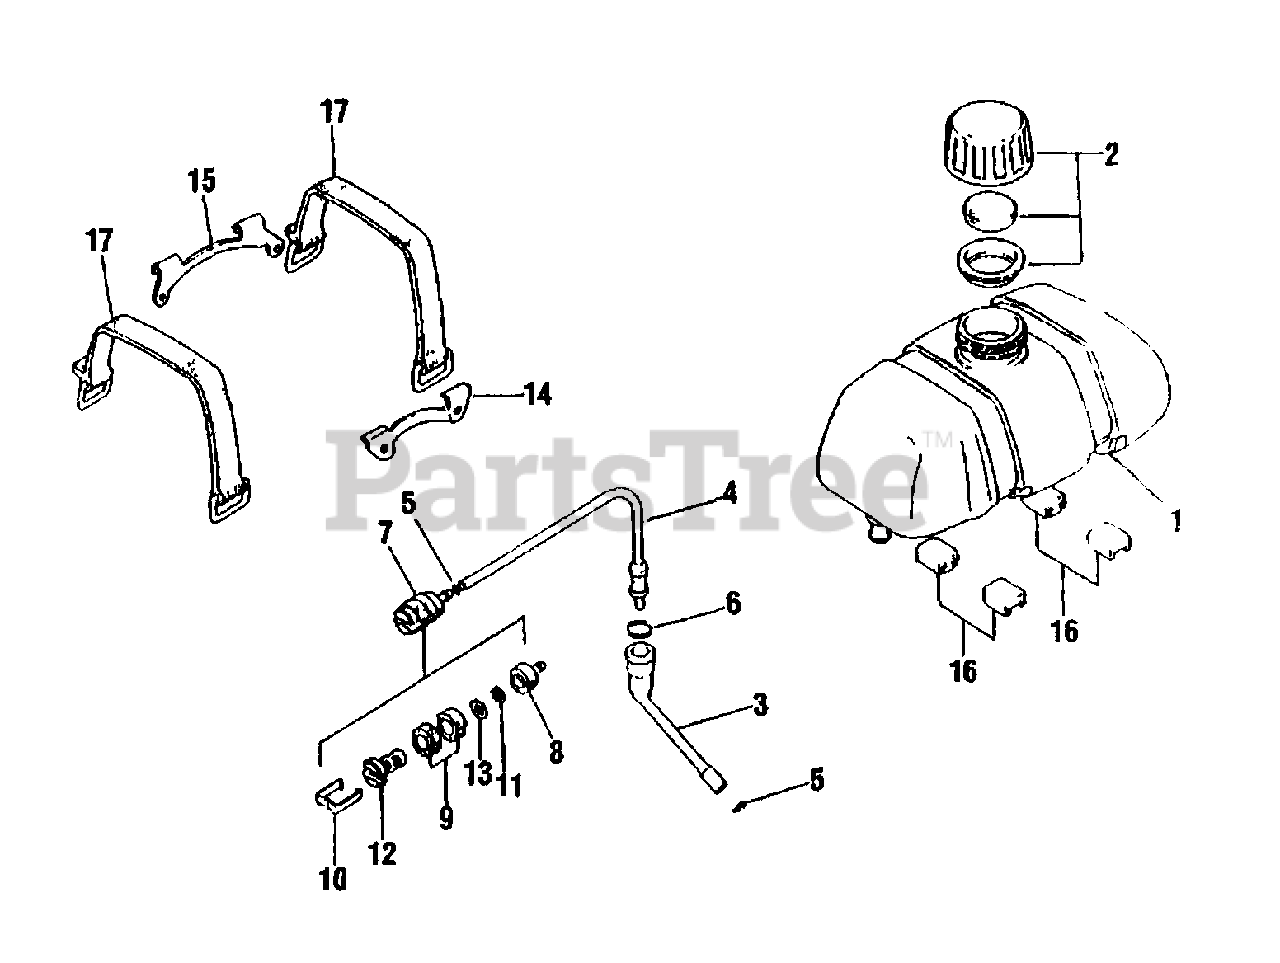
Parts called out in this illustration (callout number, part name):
1	TANK, FUEL
2	CAP, FUEL
3	PIPE - FUEL
4	TUBE, SUCTION
5	CLAMP
6	CLAMP
7	FILTER, FUEL
8	WEIGHT, FUEL FILTER
9	FILTER, FUEL
10	CLIP, FILTER
12	CASE, FILTER
13	RING, RETAINING
14	BRACKET - OUTER
15	BRACKET - INNER
16	CUSHION
17	STRAP
